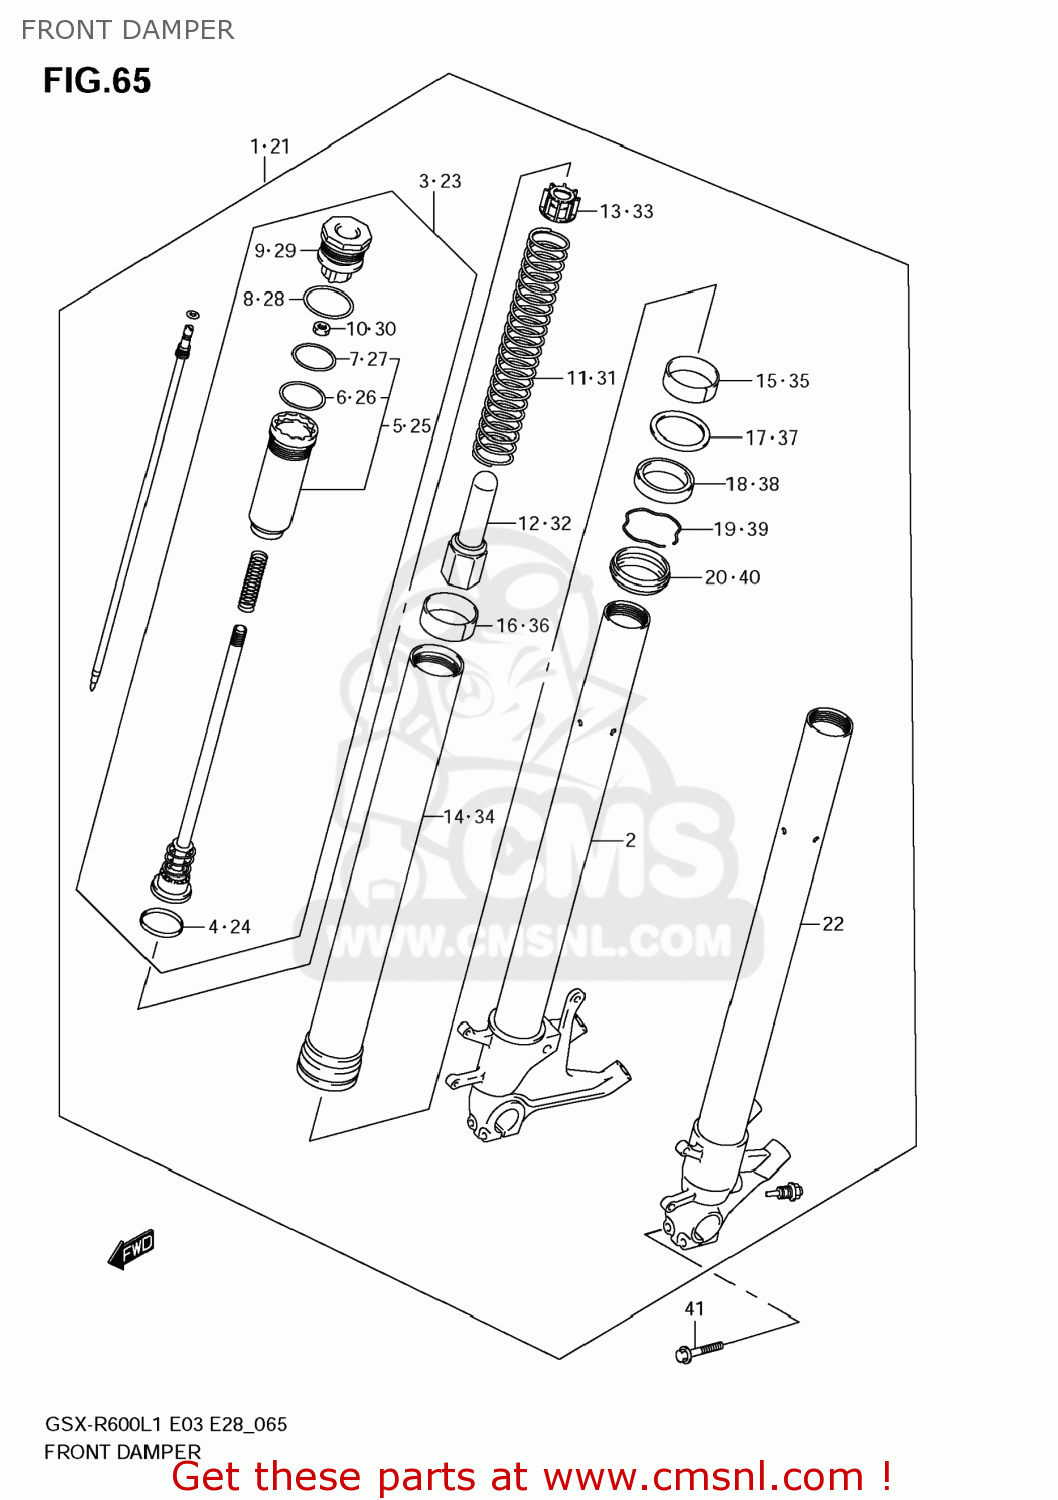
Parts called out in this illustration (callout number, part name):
1	DAMPER ASSY,FR FORK,R
2	TUBE,INNER,R
3	ROD,PISTON
4	RING,PISTON
5	CASE,ROD GUIDE
6	RING,PISTON
7	O RING
8	O RING,FORK BOLT
9	BOLT
10	NUT
11	SPRING
12	COLLAR,SPRING
13	COLLAR,SPRING
14	TUBE,OUTER
15	BUSH,GUIDE
16	BUSH,SLIDE
17	SPACER,SEAL
18	SEAL,OIL
19	CIRCLIP,FORK OIL SEAL
20	SEAL,DUST
21	DAMPER ASSY,FR FORK,L
22	TUBE,INNER,L
23	ROD,PISTON
24	RING,PISTON
25	CASE,ROD GUIDE
26	RING,PISTON
27	O RING
28	O RING,FORK BOLT
29	BOLT
30	NUT
31	SPRING
32	COLLAR,SPRING
33	COLLAR,SPRING
34	TUBE,OUTER
35	BUSH,GUIDE
36	BUSH,SLIDE
37	SPACER,SEAL
38	SEAL,OIL
39	CIRCLIP,FORK OIL SEAL
40	SEAL,DUST
41	BOLT
